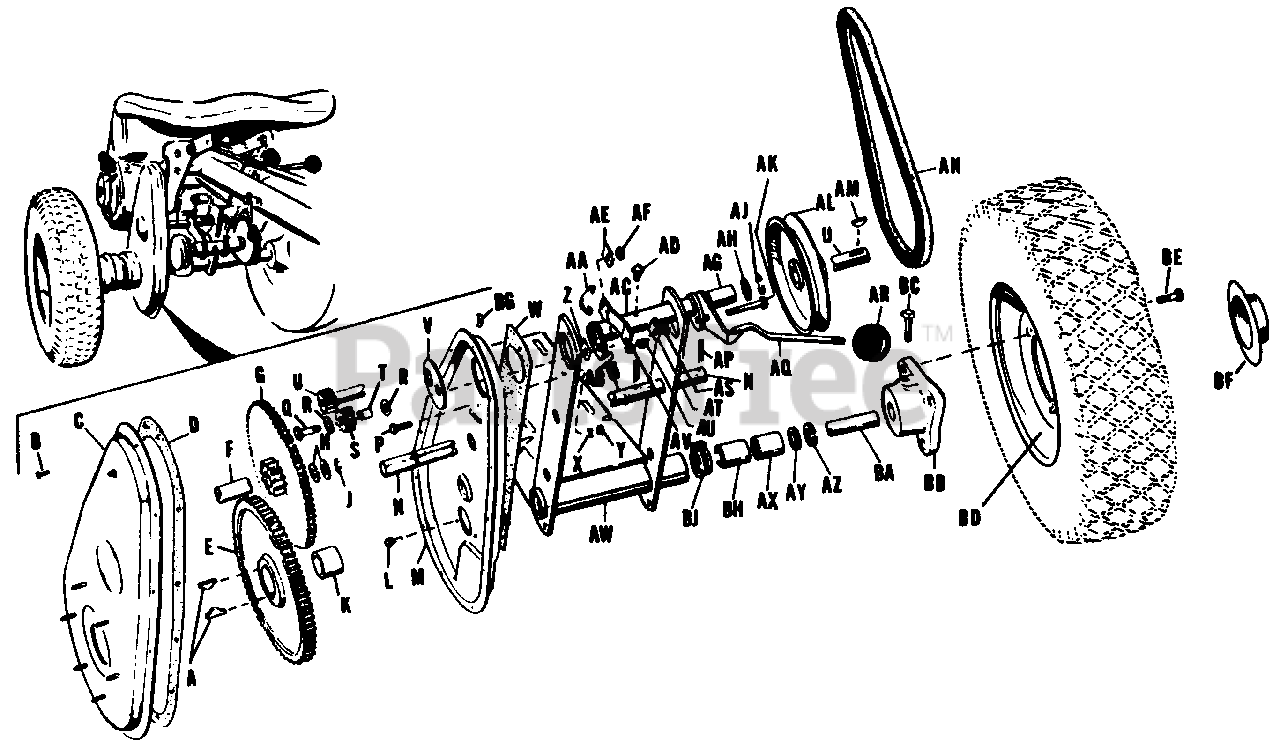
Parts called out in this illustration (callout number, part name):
A	Key, Hi Pro HP-608
B	Screw, Self Tapping #10 x 3/8
C	Cover Assembly, Gear Case
D	Gasket, Gear Case
E	Gear, Drive
F	Bearing, Intermediate Pinion
G	Gear Assembly
J	Ring, Retaining
L	Capscrew, 5/16-18 x 3/8
M	Case, Gear
N	Shaft, Intermediate
P	Capscrew, Hex Hd., 3/8-16 x 1
Q	Hex Hd., Bolt
R	Washer, Plain, 5/16
S	Pinion, Reverse
T	Spacer, Pinion
U	Pinion & Pulley Shaft
W	Gasket, Bearing Housing
X	Washer, Lock, 3/8
Y	Nut, Full Hex, 3/8-16
AA	Spring, Extension
AB	Spring, Reverse Lever
AC	Housing Assembly, Beating
AD	Grease Fitting, Alemite #1911
AE	Plate, Lock
AF	Nut, Full Hex
AJ	Ring, Retaining
AK	Capscrew, Hex Hd., 5/16-18 x 1
AL	Pulley, Transmission
AM	Key, Woodruff, 3/16 x 3/4
AP	Pin, Cotter 3/16 x 1 1/4
AQ	Lever Assembly, Shift
AS	Nut, Hex Jam, 3/8-16
AT	Plate, Friction
AV	Nut, Lock, 3/8-16
AW	Housing Assembly, Axle
AX	Bearing, Axle
AZ	Ring, Retaining
BA	Axle, Rear
BB	Hub, Wheel, L.H.
BC	Screw, Set, Sq. Hd., 3/8-16 x 1 1/4
BD	Wheel, less tire & tube
BE	Bolt, Hub
BF	Hub Cap, Rear
BG	Speed Nut
BH	Cover, Axle House
